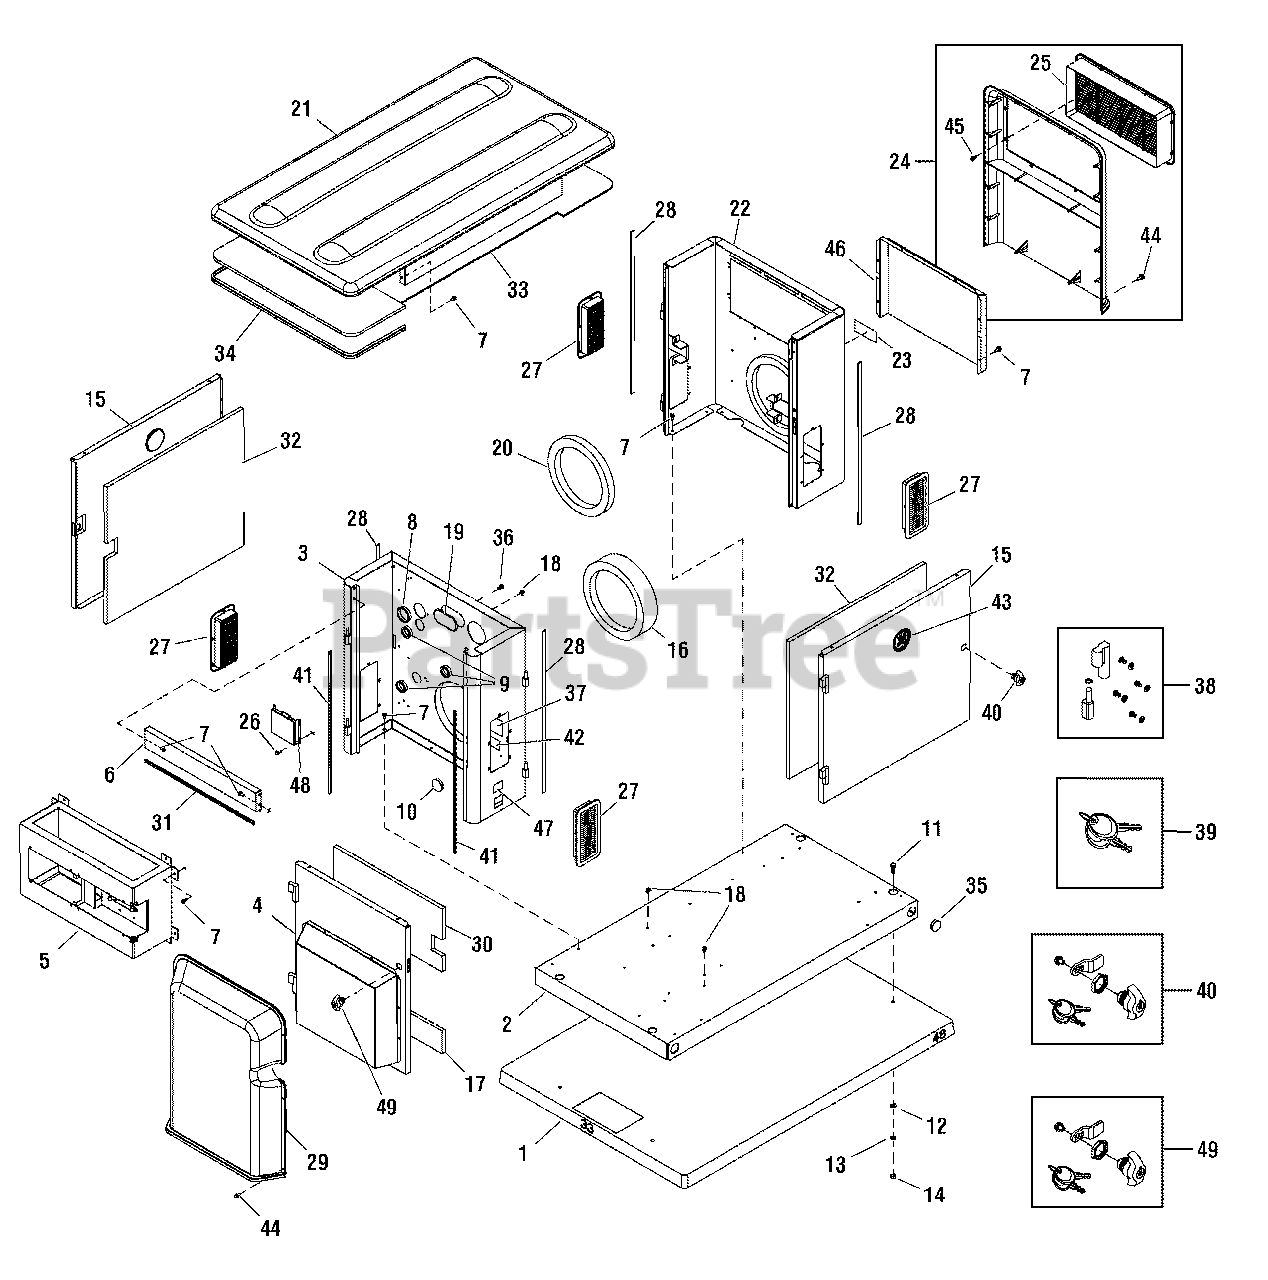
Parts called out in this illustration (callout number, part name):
3	BULKHEAD, Engine
7	BOLT
11	* CAPSCREW, Hex Head, 3/8-16 x 1
12	* WASHER, Flat, 3/8-M10
13	* WASHER, Lock, 3/8
14	* NUT, 3/8-16
16	SEAL, Foam
18	MOUNT, Tie Wrap
20	SEAL, Foam
21	ROOF
22	BULKHEAD, Alternator
42	DECAL
47	DECAL
48	REGULATOR, Voltage
